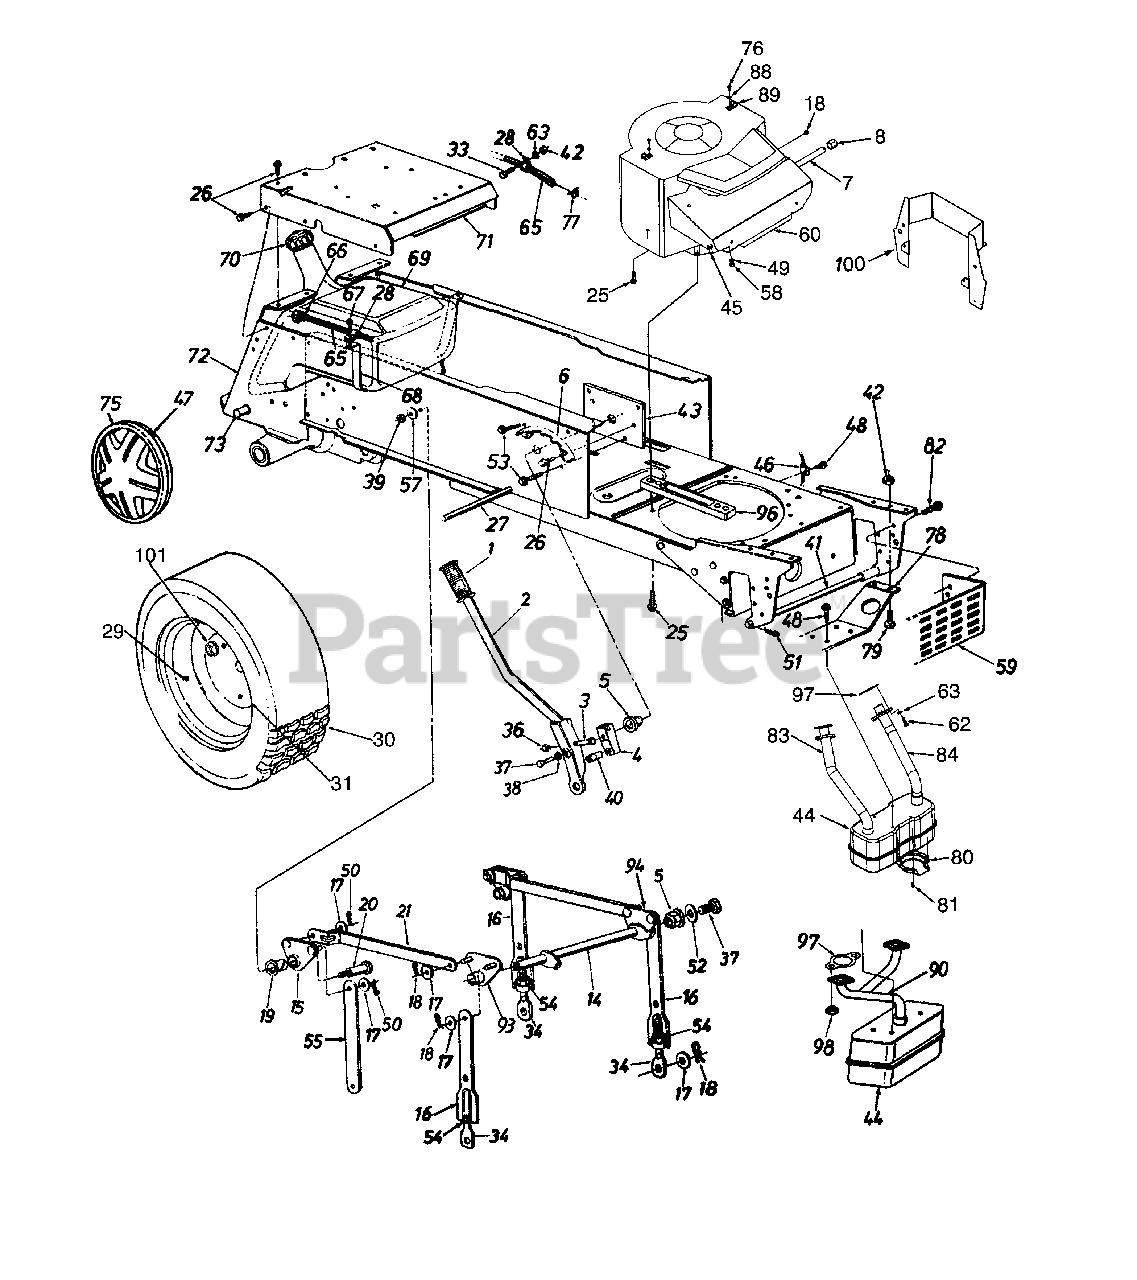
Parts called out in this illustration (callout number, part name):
1	Grip
4	Lift Shaft Drive
5	Plastic Hex Brg. 5/8" I.D.
8	Oil Drain Cap
14	Lift Shaft Ass'y.
15	Lift Pivot Brkt. Ass'y.
17	Fl-Wash. 1/2" I.D. x 1.00 " O.D. x .090"
18	Hairpin Cotter
19	Flange Brg. .63" I.D.
20	Shld. Bolt 5/8" Dia. x .96" Lg. 3/8-16
26	Hex Thd. Rolling Scr. 5/16-18x .75" Lg.
27	Running Board Rod
28	Clamp
29	Air Valve
33	Hex Bolt 1/4-20 x .62" Lg.
34	Eye Bolt Adj. Link 1/2-13 Thd.
36	Hex Cent. L-Nut 5/16-18 Thd.
37	Hex Bolt 5/16-24 x .62" Lg.
39	Hex Top L-Nut 3/8-16 Thd.
40	Compression Spring
41	Deck Connecting Rod
42	Hex Sems Nut 1/4-20 Thd.
45	Hex Bolt 5/16-18 x .75" Lg.
46	Mounting Clamp
47	Hub Cap
48	Hex TT-Tap Scr. 1/4-20 x .5" Lg.
49	L-Wash. 5/16" I.D.
50	Cotter Pin .09 Dia. x 1.0" Lg.
51	Int. Cotter Pin
52	Flat Wash. .34" I.D. x 1.12" O.D. x .125"
53	Hex AB-Tap Scr. 5/16-24 x .5"
54	Hex Nut 1/2-13 Thd.
57	Bell-Wash. .4" I.D. x 1.13" O.D.
58	Hex Nut 5/16-18 Thd. (Gr. 5)
63	L-Wash. 1/4" I.D.
65	Fuel Line 60" Lg.
66	Hose Clamp
67	Hex AB-Tap Scr. 1/4 x .62" Lg.
68	Fuel Tank Strap
69	Gas Tank
70	Gas Gauge
71	Seat Plate
75	Spring Clip
76	Truss Mach. B-Tap Scr. #10 x .5" Lg.
77	Hose Clamp
78	Muffler Mounting Brkt.
79	Hex Bolt 1/4-20 x .62" Lg.
80	Muffler Deflector
81	Hex F-Tap Scr. #8 x .32" Lg.
82	Hex TT-Tap Scr. 5/16"-18 x .62"
83	Exhaust Tube-R.H.
84	Exhaust Tube-L.H.
88	Fl-Wash. .188" I.D. x .438" O.D.
89	Clamp
90	Exhaust Pipe
93	Pivot Brkt. Ass'y.-R.H.
94	Pivot Brkt. Ass'y.-L.H.
96	Engine Mtg. Spacer
97	Gasket
98	Flange Nut M8 x 1.25 Thd.
100	Upper Heat Shield
101	Lug Nut 7/16-14 Thd.
